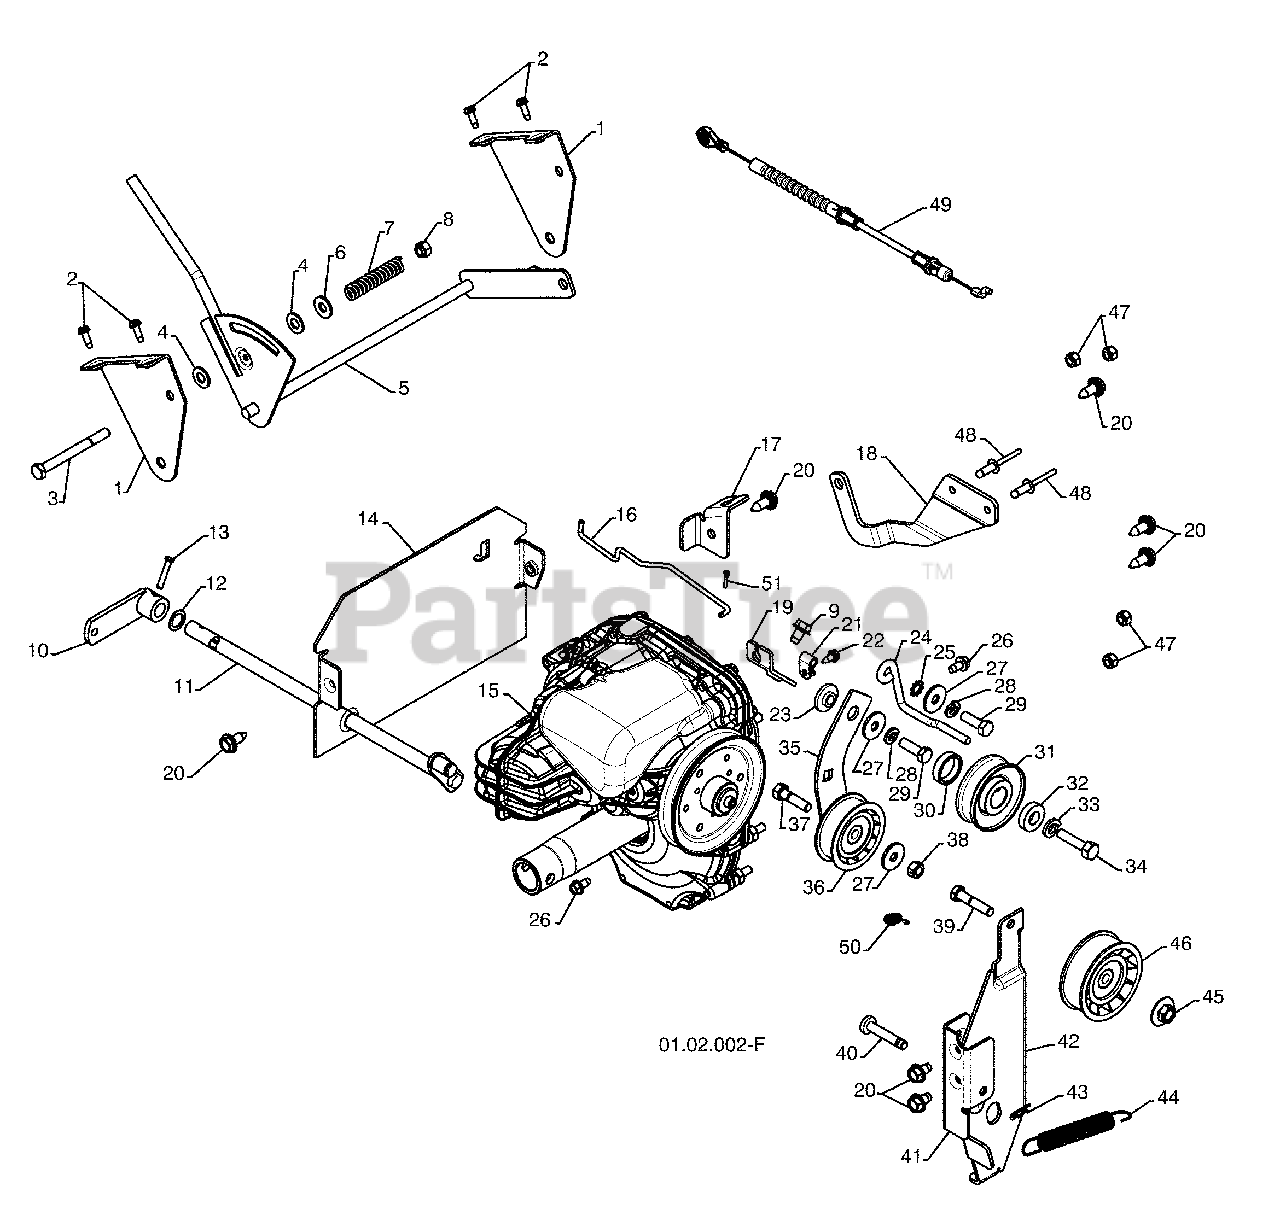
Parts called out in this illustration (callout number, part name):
1	SHIFT BRACKET
2	SCREW 10-24 X .625
3	SCREW 5/16-18 X 3.25
4	PLASTIC WASHER
5	SHIFT ASSEMBLY
7	FRICTION SPRING
8	NUT 5/16-18
9	BOLT 5/16-18 X .500
10	CONTROL ARM
11	CONTROL SHAFT
13	CLEVIS PIN
14	REAR PLATE
15	TRANSMISSION
17	REAR CABLE BRACKET
18	CONTROL ARM
19	FRONT CABLE BRACKET
20	SCREW 5/16-18 X .750
22	SCREW .12 X .50
23	BUSHING
24	BELT GUIDE
25	LOCKWASHER 5/16
26	SCREW 1/4-20 X .500
28	LOCKWASHER 5/16
29	SCREW 5/16-18 X 1.00
31	ENGINE TRACTION PULLEY
33	LOCKWASHER 3/8
34	SCREW 3/8-24 X 1.38
35	TRACTION IDLER ARM
36	IDLER PULLEY
37	SCREW 5/16-18 X 1.25
38	NUT 5/16-18
39	SCREW 5/16-18 X 1.50
41	IDLER PIVOT BRACKET
42	IDLER BRAKE ARM
44	BRAKE SPRING
45	NUT 5/16-18
46	PULLEY
47	NUT 1/4-20
48	POP RIVET 1/4 X .475
49	CLUTCH CABLE
50	TRACTION SPRING
51	RETAINER CLIP
